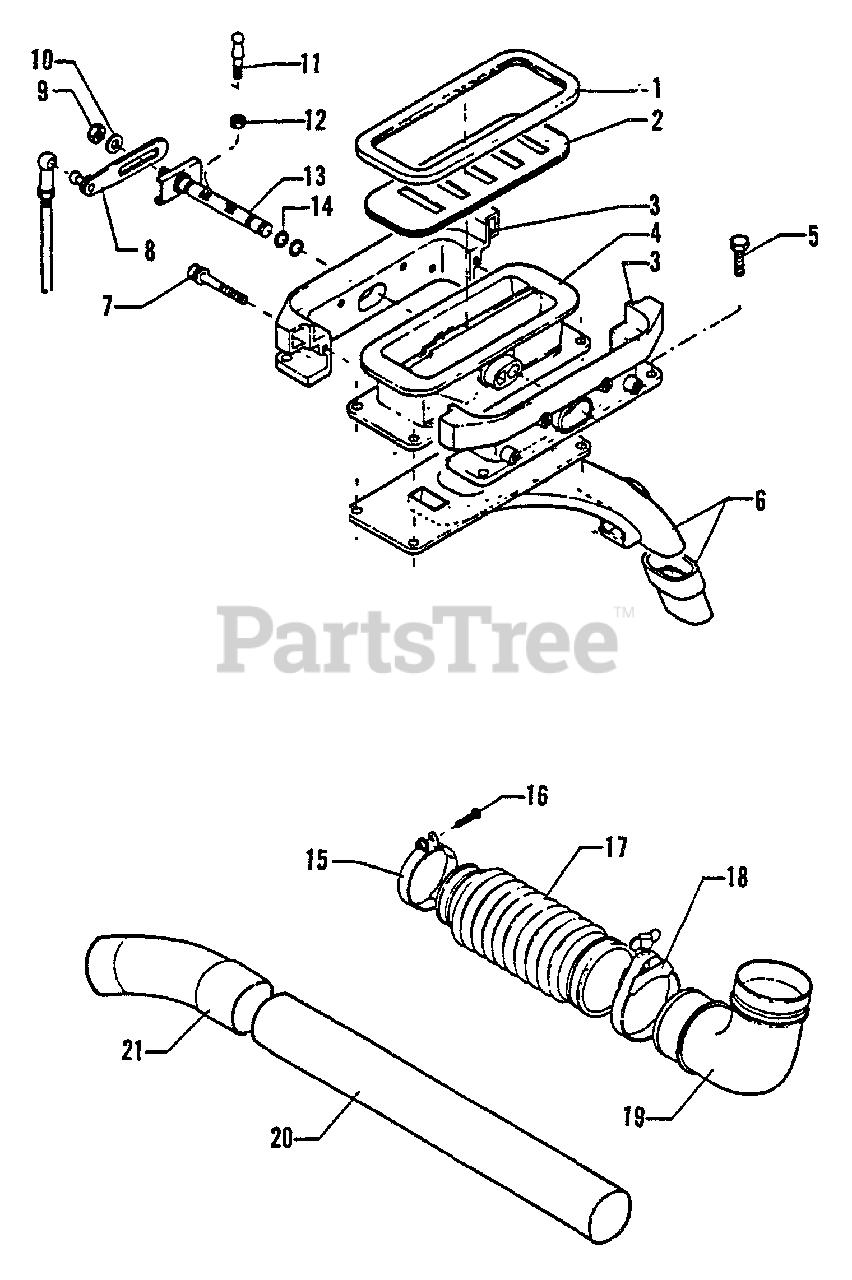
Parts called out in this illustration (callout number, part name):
2	SHUTTER ASSY
3	TANK - LOWER
4	TANK - LOWER
5	BOLT - 6X20
6	TUBE, DUST
7	SCREW - 5X30
8	ARM, SHUTTER
9	LOCKNUT - 6
10	WASHER - 6
11	JOINT
13	SHAFT, SHUTTER
14	O-RING
15	CLAMP KIT
16	SCREW - 5X25
17	TUBE, BLOWER - FLEXIBLE
18	CLAMP
19	TUBE, BLOWER - ELBOW
20	TUBE, BLOWER - STRAIGHT
21	TUBE, BLOWER - CURVED
